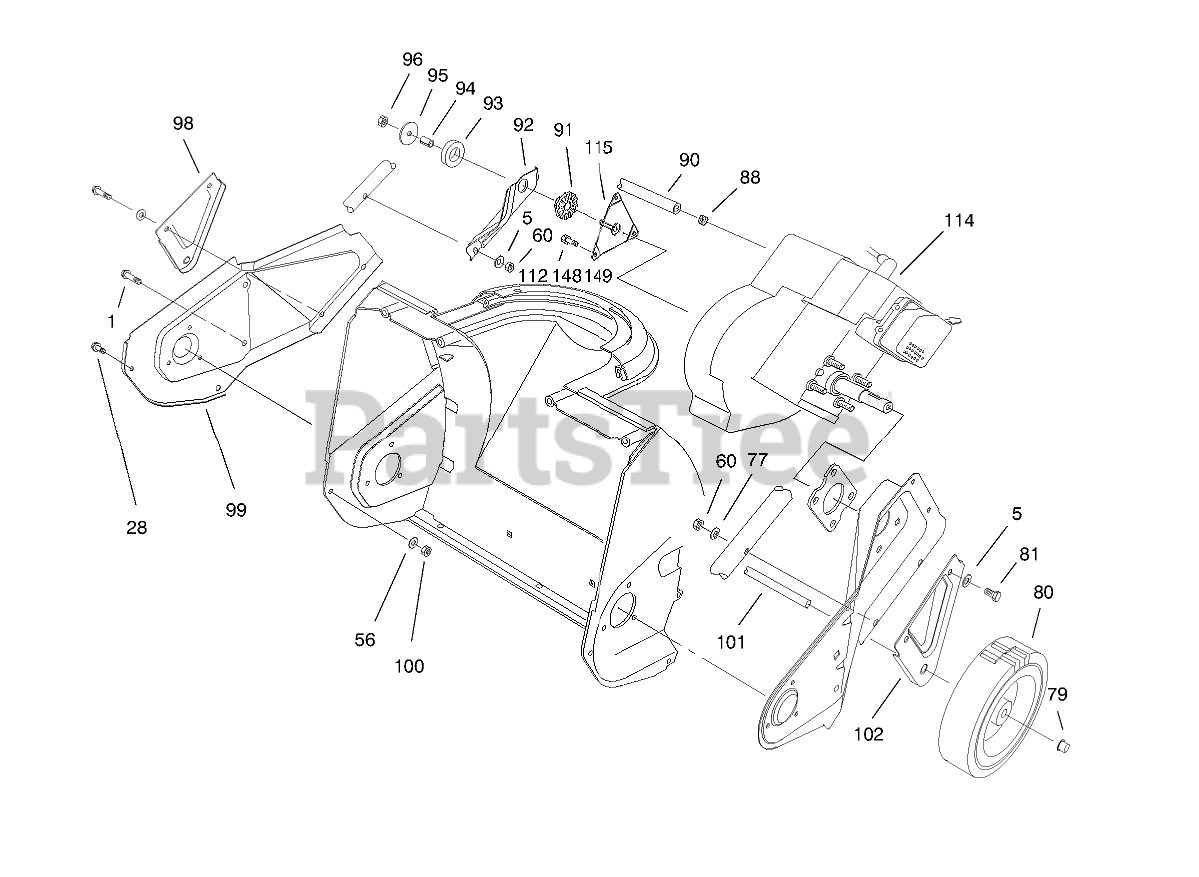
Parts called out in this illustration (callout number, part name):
1	SCREW-PLASTIC
5	WASHER-FLAT
56	WASHER-FLAT
60	NUT-LOCK, NI
77	WASHER
79	RETAINER-PUSH ON
80	WHEEL
81	SCREW-HH
88	CLAMP-HOSE
90	LINE-GAS
91	BUSHING-ISOLATOR
92	Support-Engine
93	RING-ISOLATOR
94	SPACER-TUBULAR
95	WASHER-FLAT
96	NUT-LOCK, NI
98	Bracket-Wheel
99	Sideplate-RH
100	NUT-LOCK, NI
102	Bracket-Wheel
112	SCREW
115	BRACKET AND STUD ASM
148	SCREW
149	WASHER-LOCK / EXT
